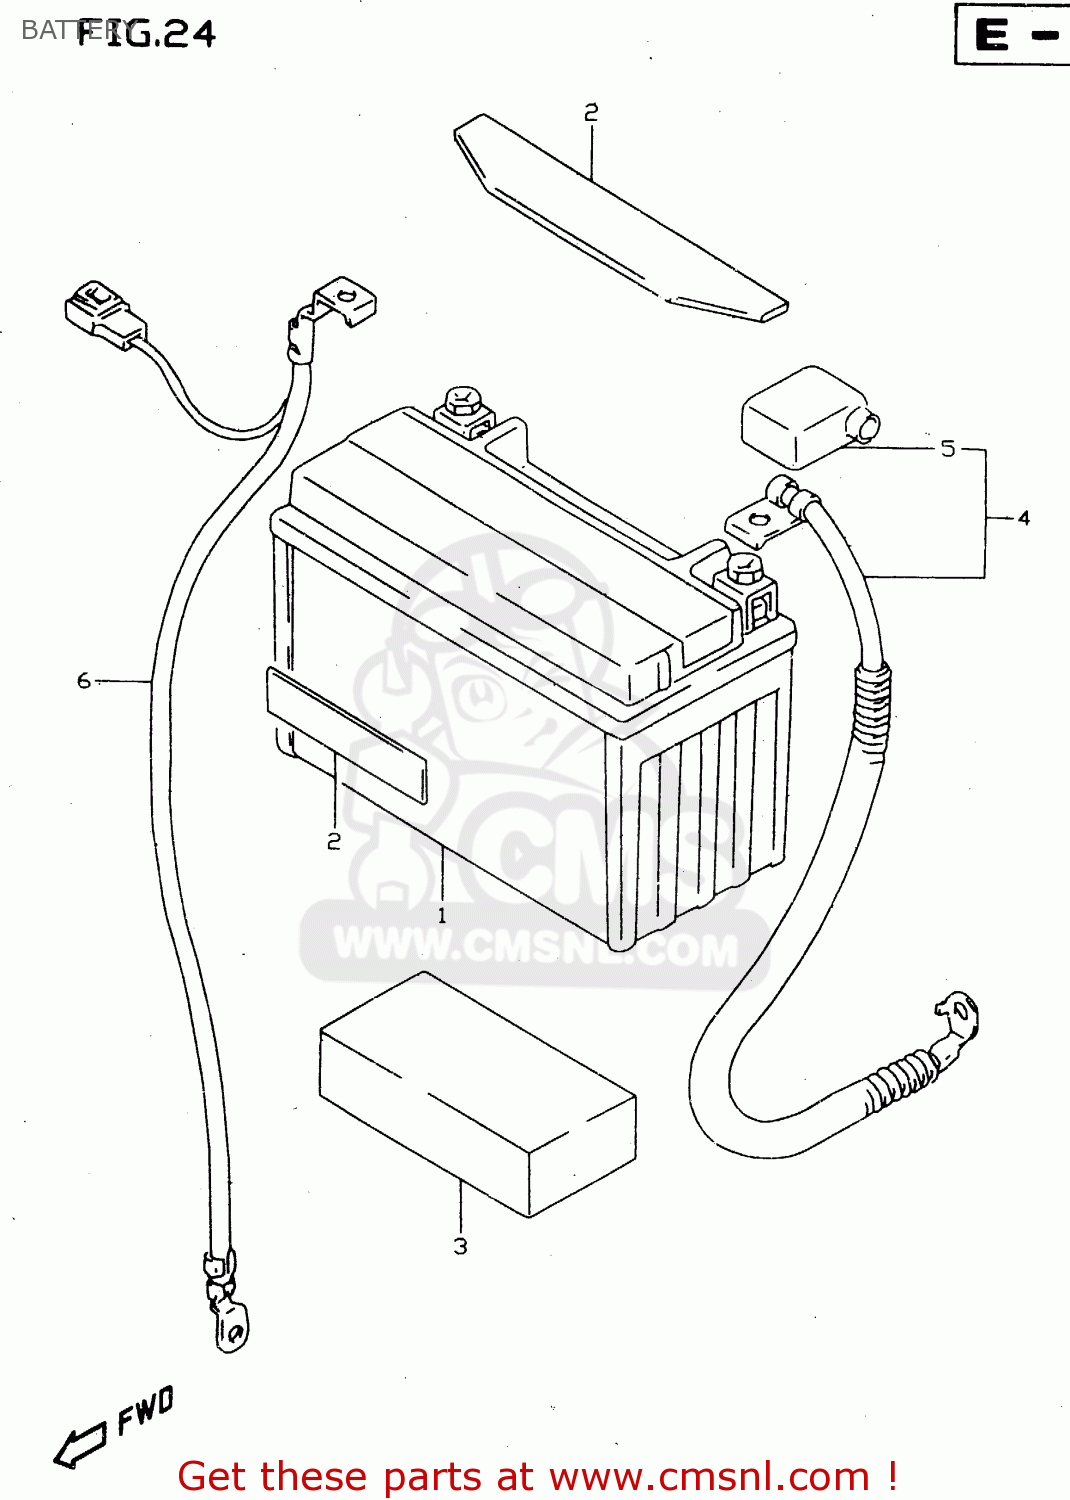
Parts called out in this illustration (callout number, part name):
1	BATTERY ASSY(YTX9-BS,12V8AH)
2	PROTECTOR(170X95X3.0)
3	CUSHION,BATTERY
4	WIRE,BATTERY PLUS LEAD
5	CAP,BATTERY PLUS
6	WIRE,BATT. MIN
